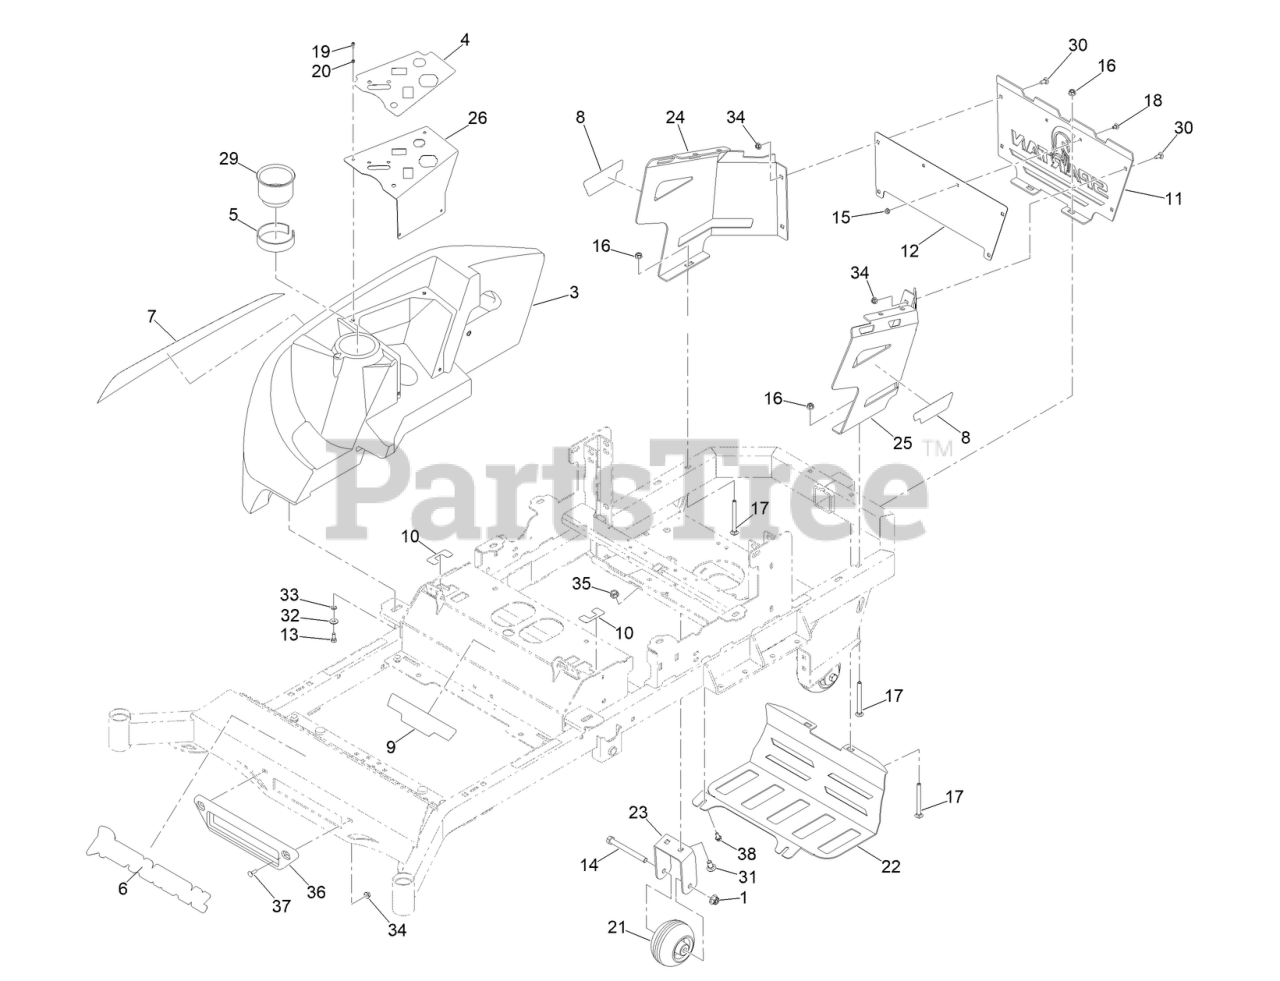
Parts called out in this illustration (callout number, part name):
1	NUT-LOCK
3	CONSOLE W/ CUPHOLDER
4	DECAL-CONTROL PANEL
5	TAPE-FOAM
6	DECAL-SPARTAN, FRONT
7	DECAL-TANK
8	DECAL-MODEL
9	DECAL-SRT-XD GT TRAC MODEL
10	DECAL-MOTION CONTROL
11	PLATE - ENGINE COWLING
12	PLATE -BACKER PLATE
13	SCREW-HH
14	SCREW-HH
15	1/4-20 HEX FLANGE NUT W/SERR ZINC
17	3/8-16 X 4 CARRIAGE BOLT ZINC
18	1/4-20 X 1/2 CARRIAGE BOLT,YZ
19	10-24 X 1/2 SOCKET C/S 18-8 SS
20	#10 SPLIT LOCKWASHER 18-8 SS
21	MWR ANTI-SCALP WHL W/O GREASE FITTING
22	MUFFLER GUARD [GRAY]
23	MWR STABILIZER MTG BRKT PAINT
24	2021 RT/SRT ENGN COWLING RTPAINTED
25	2021 RT/SRT ENGN COWLING LT PAINTED
26	RT 45 KEY MNT
29	CUP HOLDER
30	BOLT-CARR
31	SCREW-CARR
32	WASHER-LOCK
33	WASHER-FLAT
35	NUT-HF
36	MWR FT NYLON BUMPER
37	BOLT-CARR
38	BOLT-HWH
